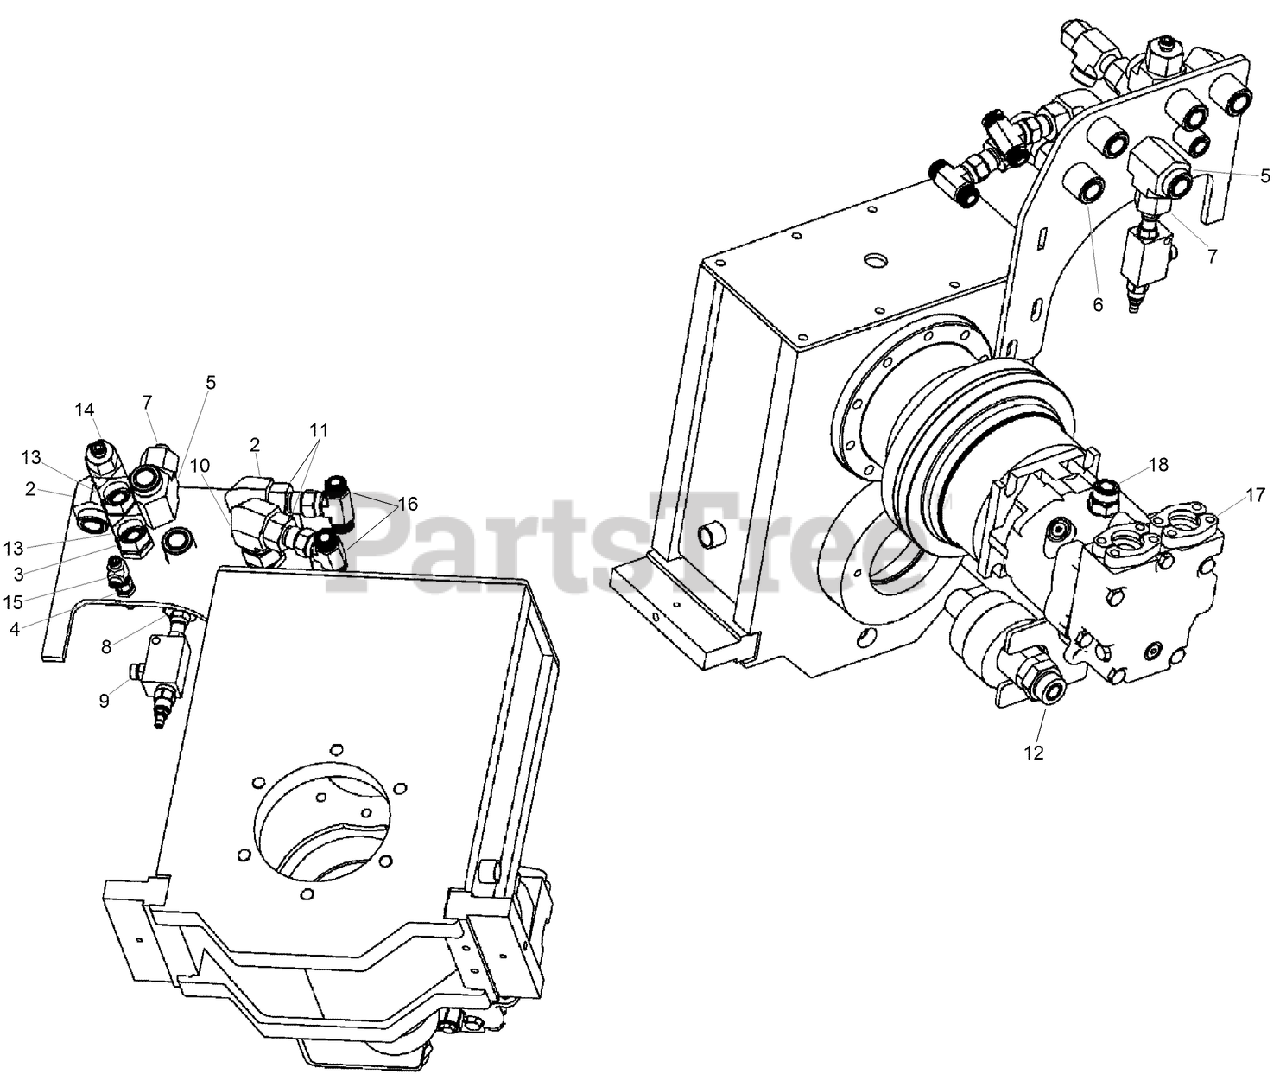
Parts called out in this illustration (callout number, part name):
2	FITTING-ELBOW, 90
3	FITTING-STRAIGHT
4	FITTING-STRAIGHT
5	FITTING-TEE, BULKHEAD
6	CONNECTION - Bulkhead, Straight ORFS
7	FITTING-REDUCER
8	CONNECTION - Straight, -6 ORFS / -6 ORB
9	CONNECTION - Straight, -6 ORFS / -6 ORB
10	CONNECTION - 90 Degree, -16 ORFS / -16 ORFS
11	FITTING-REDUCER
12	FITTING-STRAIGHT
13	FITTING-TEE
14	FITTING-REDUCER
15	CONNECTION - Run Tee, -4 ORFS / -4 ORFS
16	CONNECTION - Branch Tee, -10 ORFS / -10 ORFS
17	KIT, SPLIT FLANGE -16 SAE, w/o Rings and Bolts
18	CONNECTION - Straight, -12 ORFS / -12 ORB
